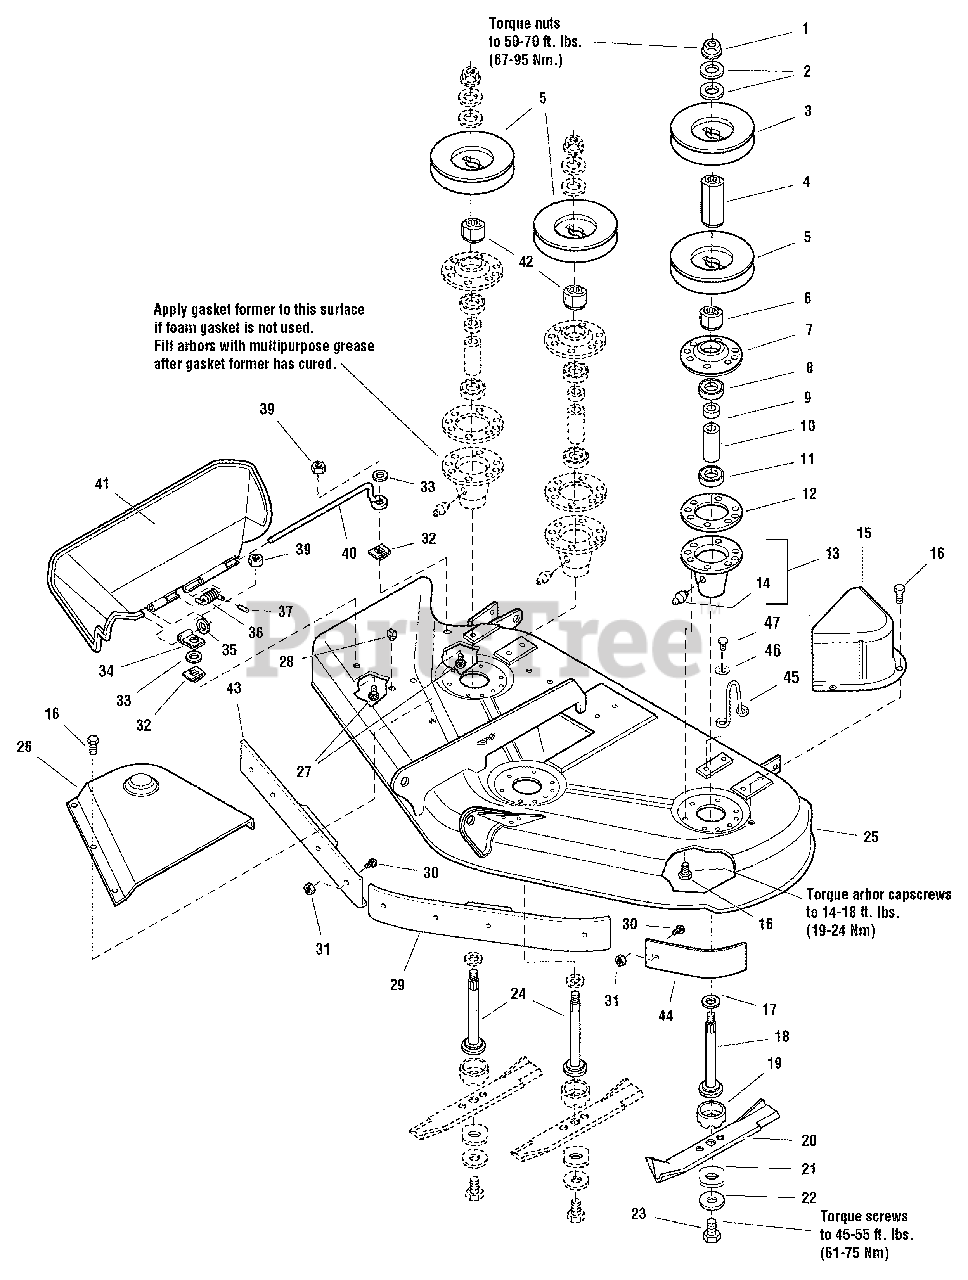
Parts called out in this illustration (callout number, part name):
1	NUT, Hex Flange, 9/16-18
2	WASHER, Bellevilled, 9/16
4	HUB, Double Pulley
6	HUB, Double Pulley
7	COVER, Arbor Housing
8	BEARING, Ball, 3/4 x 1-3/4 x 5/8
9	SPACER, 21/32 x 3/4 x 5/8
10	SPACER, 11/16 x 5/32 x 2-11/16
11	BEARING, Ball, 11/16 x 1-9/16 x 15/32
12	GASKET, Foam
13	HOUSING ASSEMBLY, Arbor Bottom, w/Lube Fitting
14	FITTING, Grease
15	COVER, Arbor
16	CAPSCREW, Hex Head Taptite, 5/16-18 x 3/4
17	WASHER, Bellevilled, 9/16, Black
18	SHAFT, Arbor (LH)
19	SHIELD, Grass, Lower
20	BLADE, Mower, 18-1/8
21	WASHER, Hex, 11/16 x 2
22	WASHER, Spring 15/32, Black
23	CAPSCREW, Hex Head, 7/16-14 x 1
24	SHAFT, Arbor (Center & RH)
25	MOWER HOUSING ASSEMBLY, 50" Mower (Orange)
25	MOWER HOUSING ASSEMBLY, 50" Mower (Red)
26	COVER, Arbor
27	BOLT, Carriage, 1/4-20 x 7/8
29	BAFFLE, Anti-Blowout, LH
30	CARRIAGE BOLT, 5/16-18 x 3/4
31	NUT, Hex, Whizlock, 5/16-18
32	NUT, Push
33	WASHER, 1/4, Black
35	WASHER, 5/16, Black
36	SPRING
37	CAP, Spring End
39	NUT, Hex, 1/4-20 ESNA
40	ROD, Deflector, Front
41	DEFLECTOR, Plastic
42	HUB, Pulley, Center & RH
43	BAFFLE, Anti-Blowout, RH
44	BAFFLE, Anit-Blowout
46	WASHER
47	CAPSCREW, Taptite 5/16-18 x 3/4
